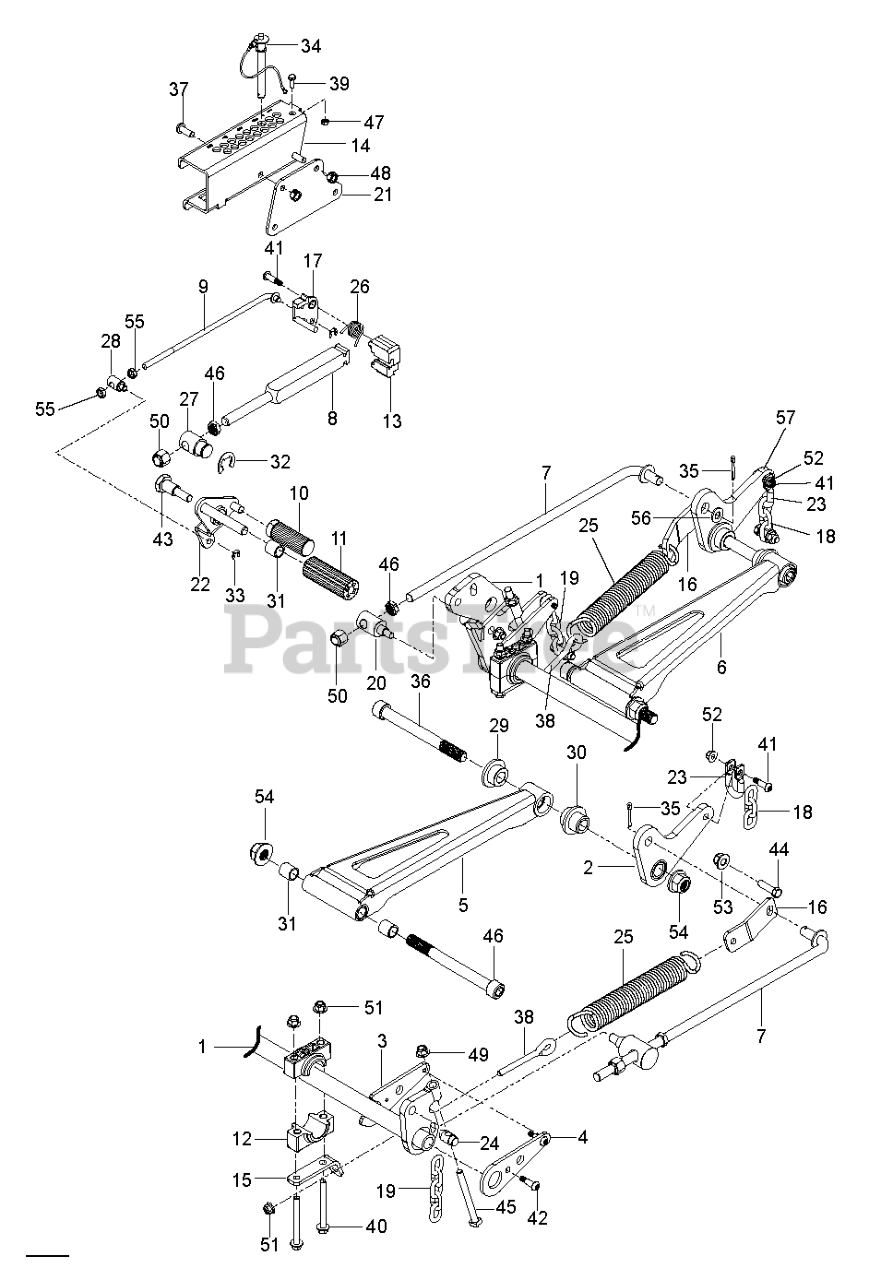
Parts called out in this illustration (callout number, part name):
1	SHAFT.WLDMNT.FRNT.DECK.LFT.PNT
2	KIT.ARM.BELLCRANK/BUSHINGS.RT
3	ARM.DECK.LIFT.INNER.BLACK
4	ARM.LIFT.DECK.OUTER.POWER.BLK
5	ARM.DRAWBAR.LH
6	ARM.DRAWBAR.RH
7	ROD. CONNECTING
8	ROD.HEIGHT.GAUGE
9	ROD.RELEASE.CONNECTING.TOE
10	PEDAL, DECK HEIGHT
11	PAD, FOOT PEDAL
12	BLOCK, PILLOW
13	BLOCK.ROD.END
14	BRACKET.ADJUSTMENT.HEIGHT.ORNG
15	BRACKET.PILLOW.BLOCK.PNT.BLACK
16	BRACKET SPRING BLACK (X428)
17	KIT.LEVER.LOCK.W/BUSHING
18	LIFT CHAIN - 3 LINK
19	LIFT CHAIN
20	PIVOT.CONNECTING.ROD
21	PLATE.HEIGHT.GAUGE.MOUNT.PNT
22	LEVER ASSY TOE RELEASE
23	SHACKLE.CHAIN
24	SHAFT.TRUNNION.ATTACH
25	SPRING EXTENSION, DECK LIFT, H
26	SPRING.TORSION.RELEASE.LEVER
27	SWIVEL.HEIGHT.BAR
28	SWIVEL.TOP.RELEASE
29	BUSHING.DECK.INNER
30	BUSHING.DECK.OUTER
31	BUSHING, SLEEVE 3/4 X 1.0
32	E-RING 1"
33	E RING 3/8"
34	PIN.PUSH.BUTTON.DETENT..5X3.5
35	COTTER PIN 1/8 X 2
36	SCREW.SOCKET.HEADCP.3/4-10X7.5
37	SCREW.BUTTON.HEAD.CAP.3/8-16X1
38	EYE BOLT, 3/8 X 4"
39	HCS 1/4C X 3/4 HCS
40	SCREW.HHFS3/8-16X3.75.GR8
41	SCREW.SHOULDER.375X875.5/16-18
42	SCREW.SHLDR..375.5/16-18.88.LG
43	BOLT, SHOULDER
44	HCS 7/16C X 1 1/2
45	SCREW.HHC.7/16-14 X 4.50
46	NUT.HH.THIN.NYL.5/8-11 GR5
47	NUT.1/4-20.HEX.NYLOC.ZD
48	NUT 3/8C CENTERBLOCK
49	7/16-14 HEX NUT W/NYL RING ZD
50	NUT 5/8-11 NYLOC
51	NUT 3/8-16 HEX FLG NYLOC ZD
52	5/16-18 NYLOC FLANGE NUT
53	NUT 7/16-14 HEX WHIZ LK
54	NUT.HEX.FLANGED.3/4-10.NYLOK
55	NUT 3/8-24 JAM
57	KIT.ARM.BELLCRANK/BUSHINGS.RT
